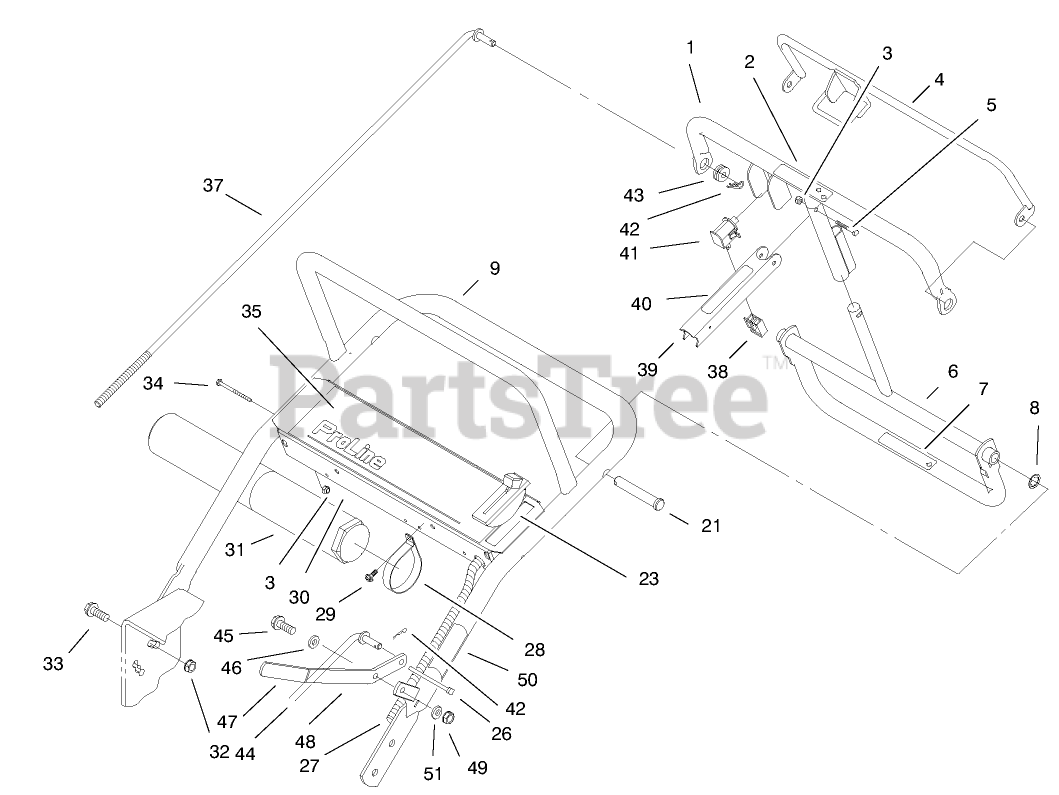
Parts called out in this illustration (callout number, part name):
1	Control Bar
2	DECAL-BAR, CONTROL
3	NUT-LOCK, NI
4	Bail ASM
5	SCREW-SHH
6	Pivot-Control
7	DECAL-REVERSE
8	NUT-PUSH-ON, CIRCULAR
9	Upper Handle ASM
21	PIN-CLEVIS
23	Throttle Control
26	TIE-CABLE
27	Wire Harness-Kohler
28	CLAMP-R
29	SCREW-HWHTF
30	Control Panel ASM
31	TUBE-MANUAL
32	NUT-HF
33	SCREW-HHF
34	SCREW-SHH
35	DECAL-CONTROL PANEL
37	Rod-Control
38	CONNECTOR-BODY
39	Lever-Parking Brake
40	DECAL-PARKING BRAKE CE
41	SWITCH
42	PIN-COTTER
43	GROMMET-RUBBER
44	Linkage-Blade Drive
45	SCREW-SHOULDER, HWH
46	WASHER-THRUST
47	Grip
48	Lever-Blade Engagement
49	NUT-HEX
50	Decal-Blade Engagement
51	WASHER-FLAT
